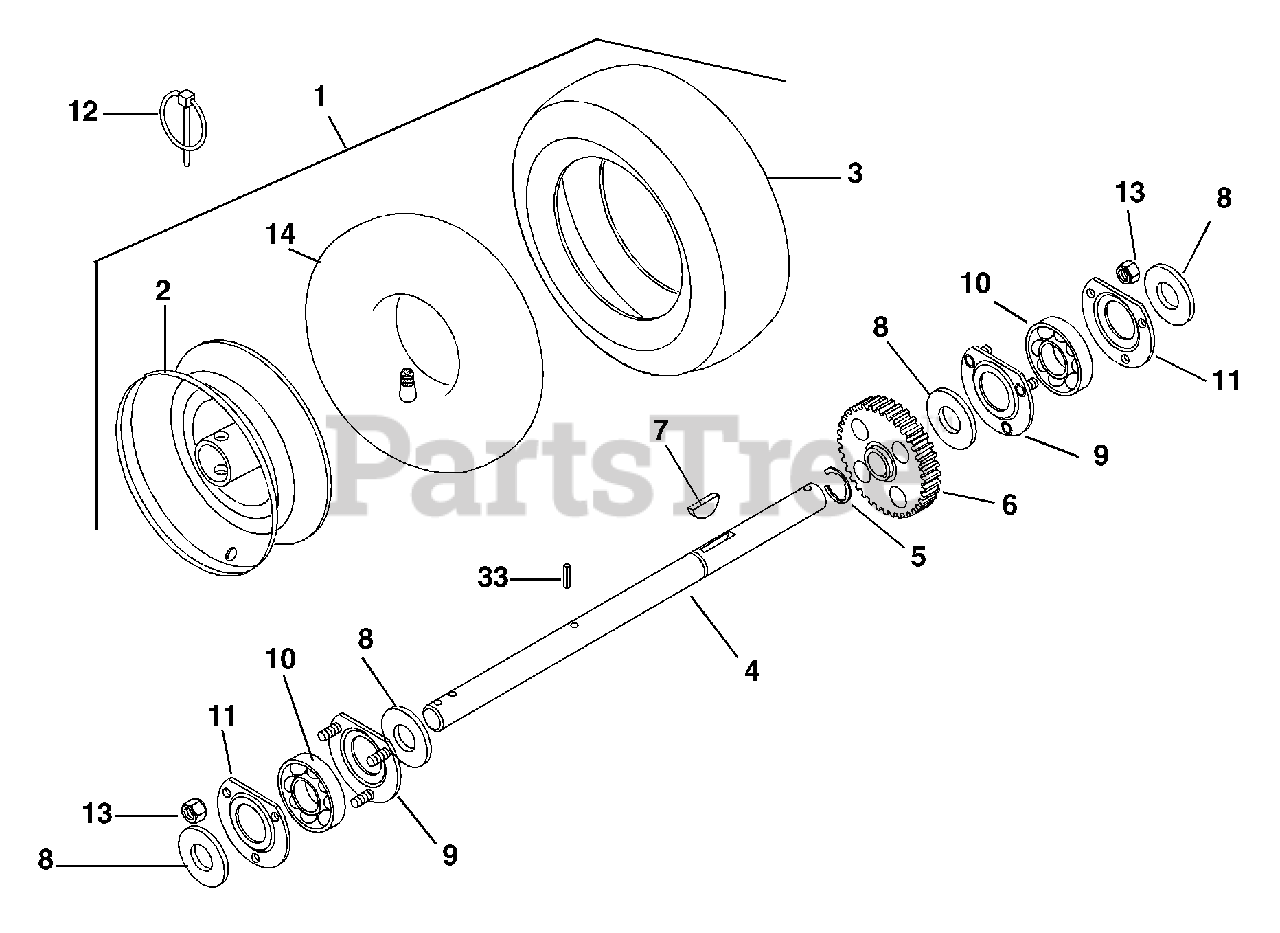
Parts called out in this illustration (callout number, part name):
1	TIRE/WHEEL ASSEMBLY 16X6.50-8
2	WHL 6.50X8
3	TIRE 4.80-8 NHS
4	SHAFT, AXLE
5	RG-RTNG-EXT. .875X.050
6	GEAR, SPUR
7	KEY-WDRF .25X.875X.375 SAE A
8	WSHR-FL-STL .880X1.250X.062YWZ
9	BEARING FLANGE
10	BRG-BALL .876 X 1.750 X .50
11	BEARING FLANGE
12	PIN-LOK .31X1.75
13	@NUT-LK-CTR .25-20 YWZC
14	TUBE
33	PIN-ROLL .188X1.50
